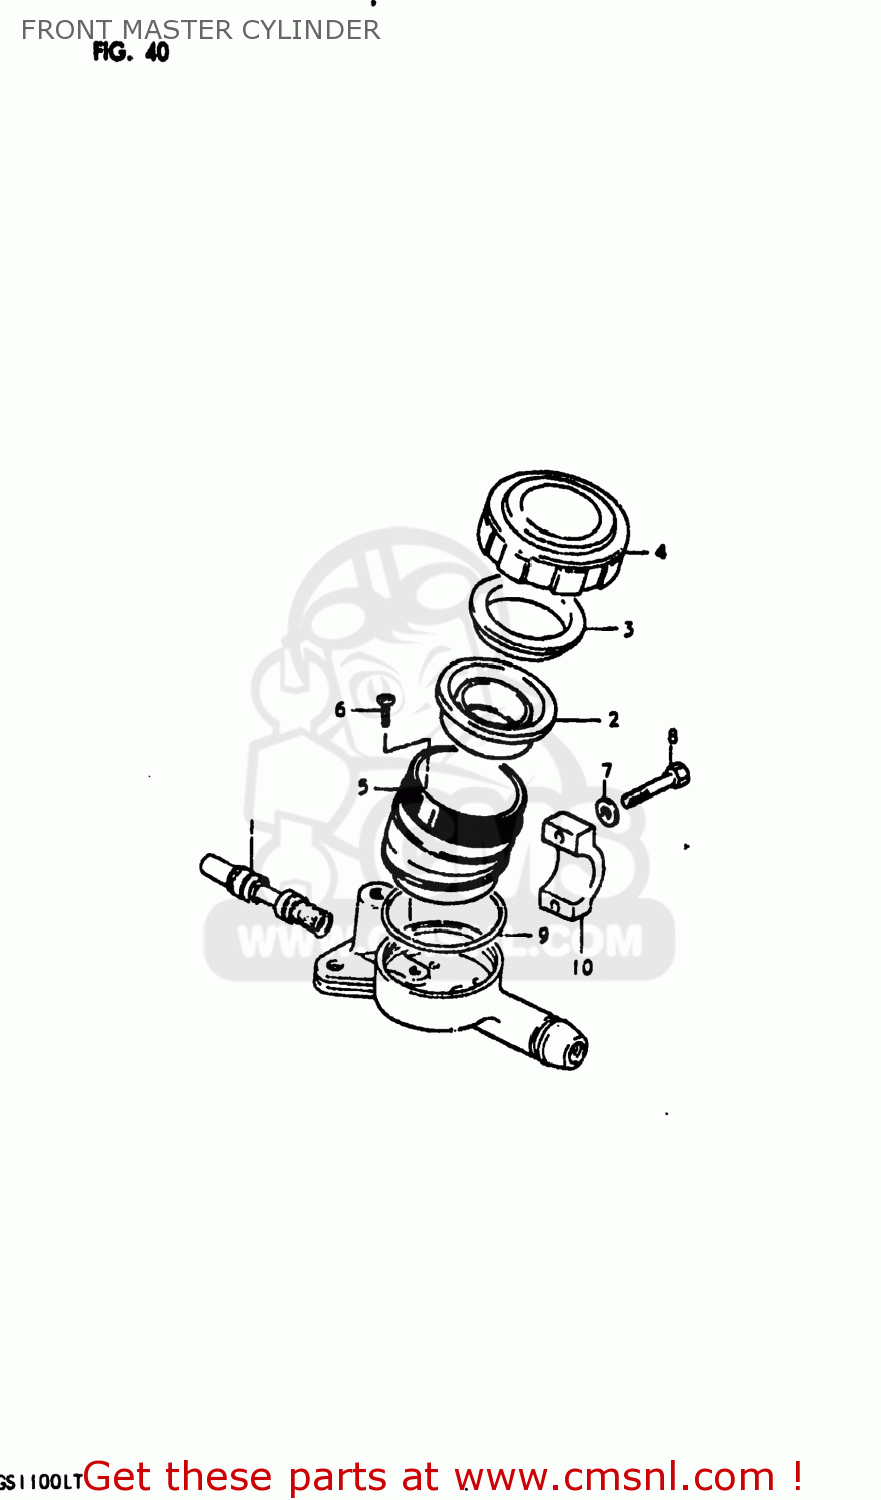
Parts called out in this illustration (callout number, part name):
1	PISTON & CUP SET
2	DIAPHRAGM
3	PLATE
4	CAP,MASTER CYLINDER,REAR
5	RESERVOIR
6	SCREW,MASTER CYLINDER
7	WASHER
8	BOLT
9	O RING
10	HOLDER,MASTER CYLINDER
